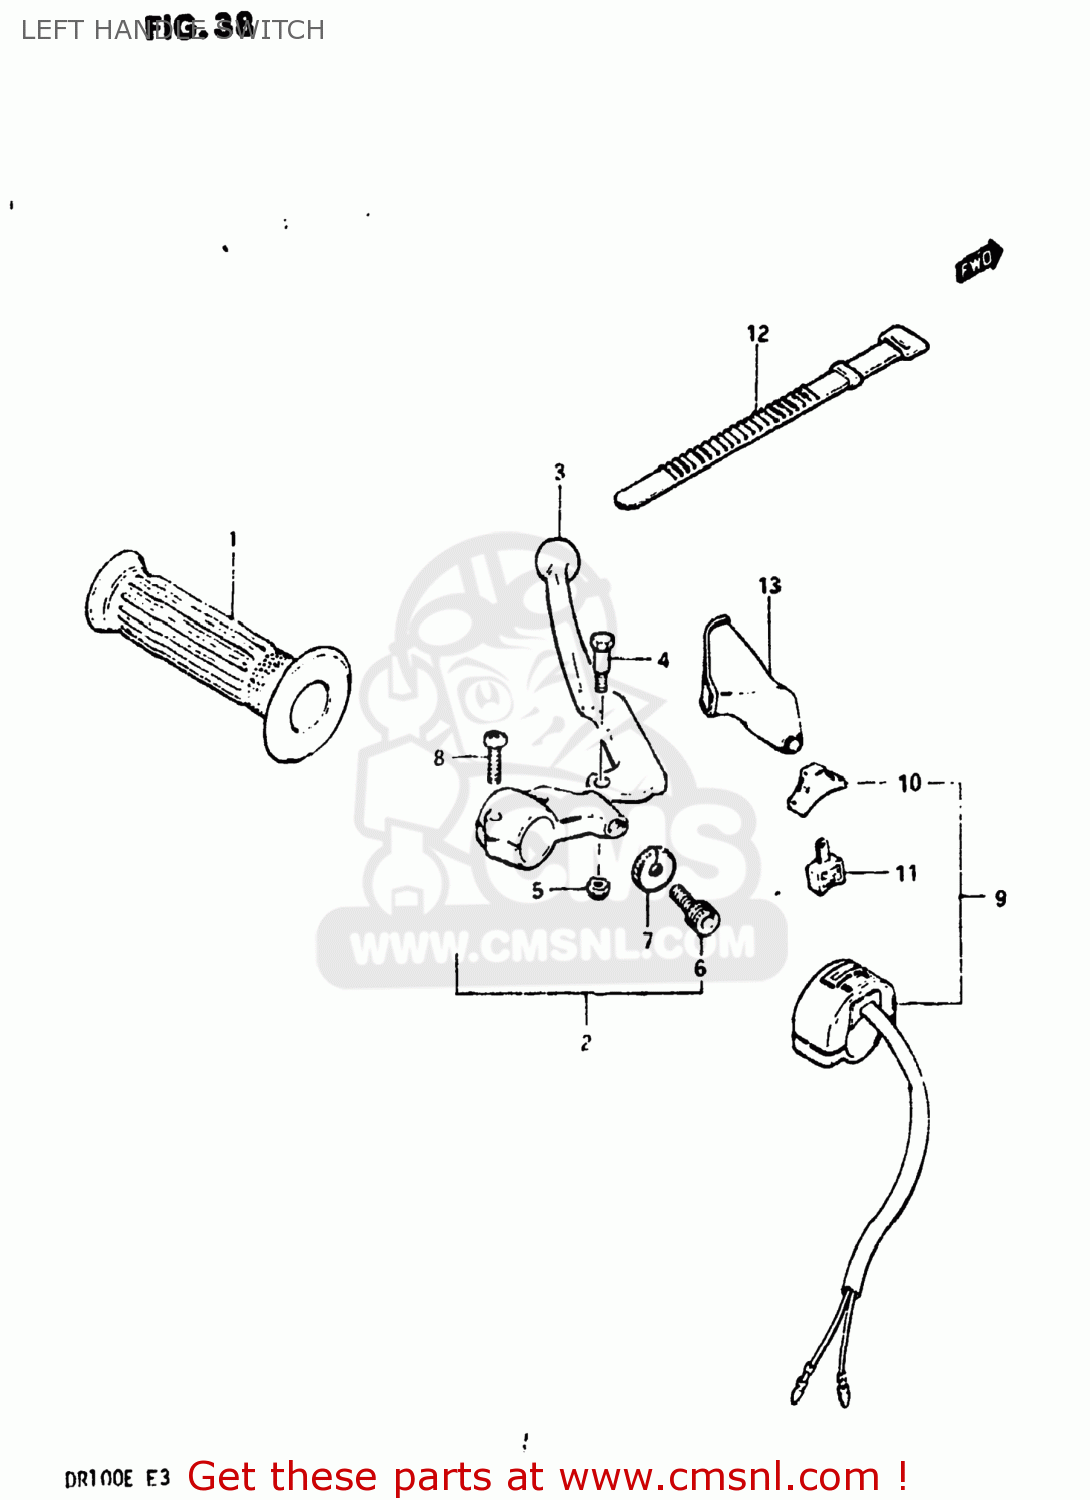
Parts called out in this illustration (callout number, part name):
1	GRIP,L
2	LEVER ASSY,CLUTCH
3	LEVER,CLUTCH
4	BOLT,LEVER
5	NUT 6MM
6	ADJUSTER,CABLE
7	NUT,CABLE ADJUSTER
8	SCREW
9	SWITCH ASSY,LIGHTING
10	KNOB,LIGHTING & DIMMER
11	BLOCK,LIGHTING/DIMMER
12	CLAMP(L:120)
13	COVER,CLUTCH LEVER
